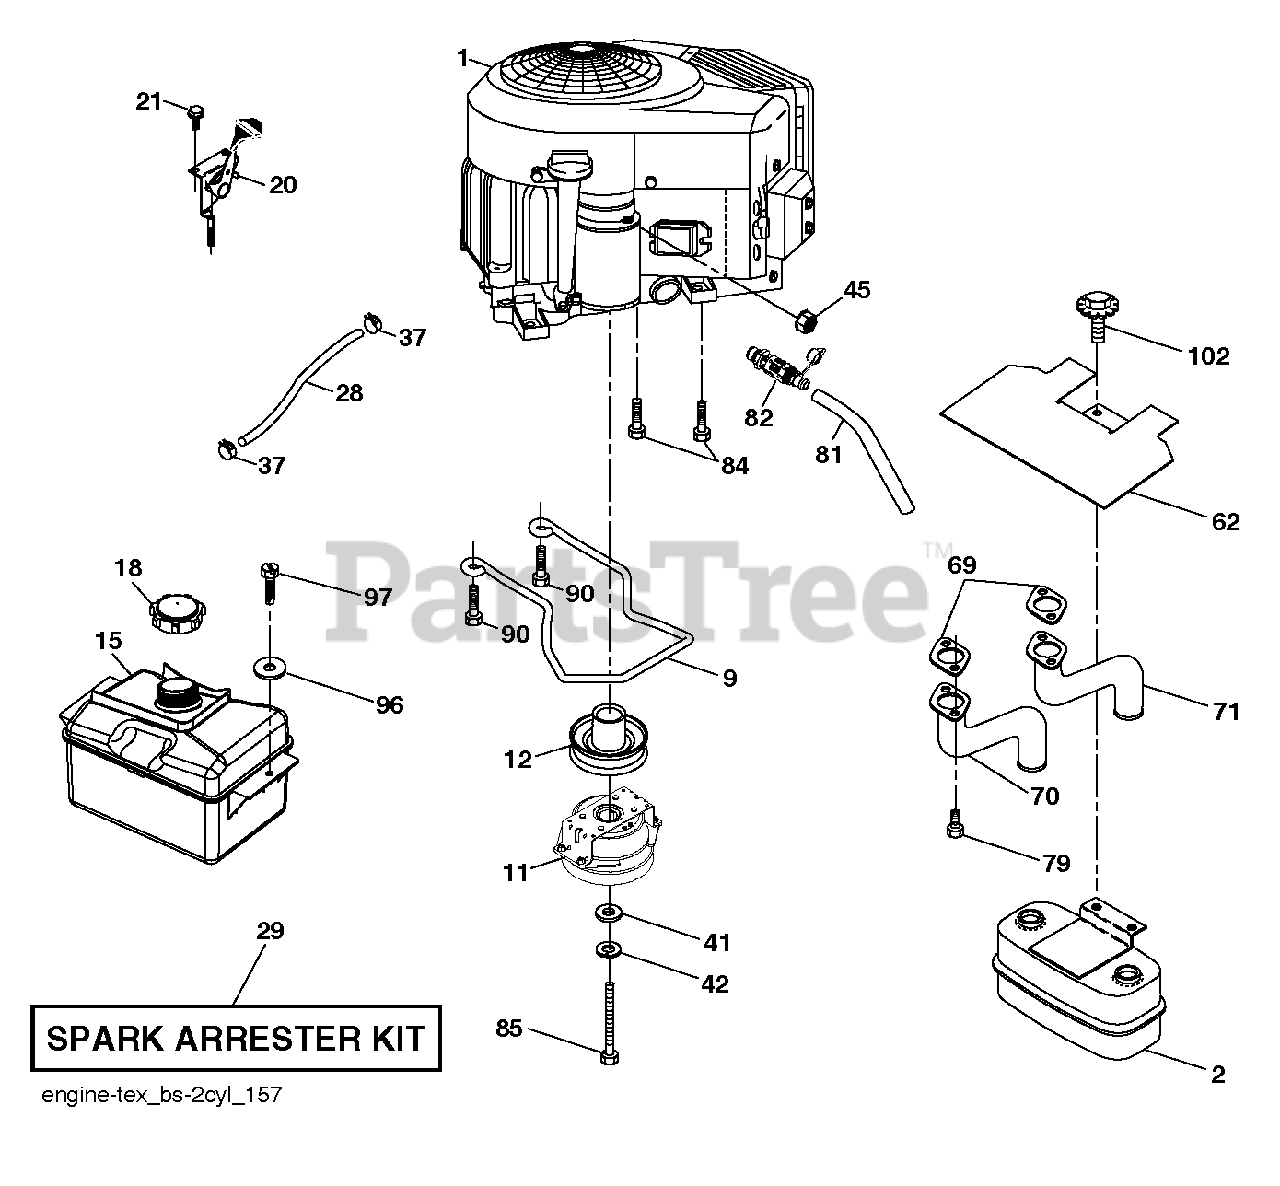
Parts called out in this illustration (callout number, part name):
2	MUFFLER.ASM.TWN.EXTNDED.DFLCTR
9	KEEPER.BELT.ENG.4.25"2.BLT.431
11	CLUTCH.OGURA.5.0PD.GT1.5A-EH07
12	PULLEY.ENGINE.TUFFTORQ
15	TANK.ASSEMBL.2.5GAL.NON-EPA
18	CAP ASM.FUEL.2.25"FR.
20	THROTTLE.COBRA.38"READSTART.BK
21	SCREW.#10 X 0.750.BOS
28	LINE.FUEL.20
29	KIT.SPARK ARRESTOR 794945 B&S
37	HOSE CLAMP
42	WASHER 7/16 LOCK
45	NUT
62	SHIELD.HEAT.MUFFLER
69	GASKET.MUFFLER
70	EXHAUST.TUBE.LH.BS/TWIN
71	EXHAUST.TUBE.RH.B&S.TWIN.INTEK
79	SCREW.SOCKET.HEAD.5/16-18
81	TUBE, DRAIN OIL ASM.
82	VALUE.OIL.DRAIN
84	SCREW.3/8-16
85	BOLT.HEX.7/16-20X3.75.GR5.RED
90	SCREW 3/8-16X1
97	SCREW HEXWSHR 1/4-20X3/4
102	SCREW
